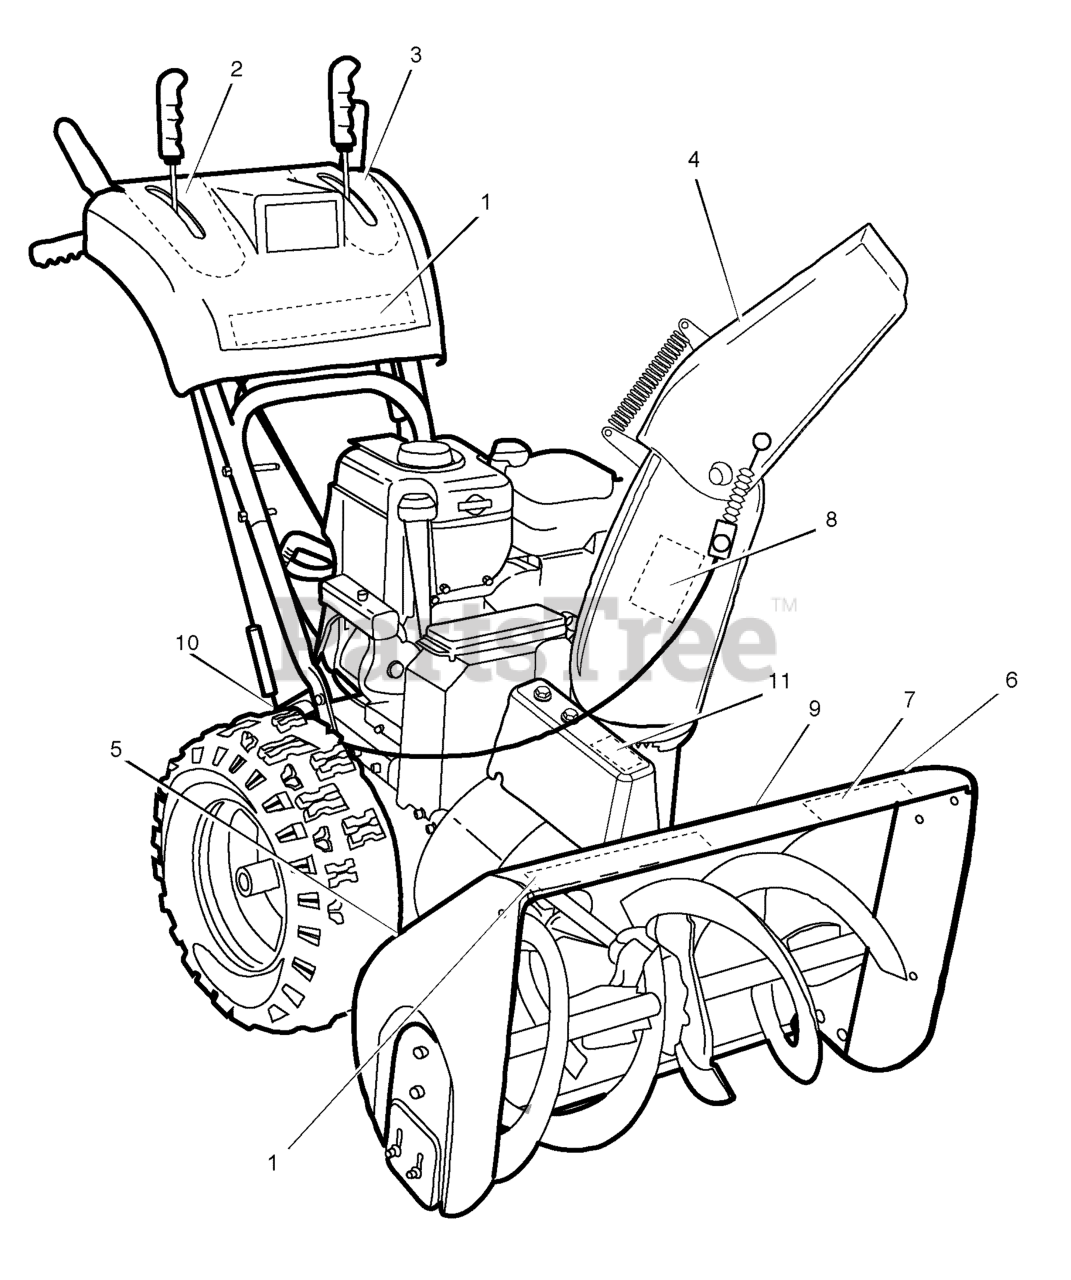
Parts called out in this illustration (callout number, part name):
1	DECAL, CANADIANA
2	DECAL, CANADIANA 160/84 SPEED
3	DECAL, REMOTE CHUTE TRACTION
4	DECAL, ISO CHUTE
5	DECAL, ISO AUGER
6	DECAL, FACE HEAD PHONES
7	DECAL, 1450/74 TOP AUGER WHITE
8	DECAL, POWER 2 STEER
9	DECAL, 104db CE
10	DECAL, ID PLATE
11	DECAL, PINCH POINT ELECTRIC CHUTE
